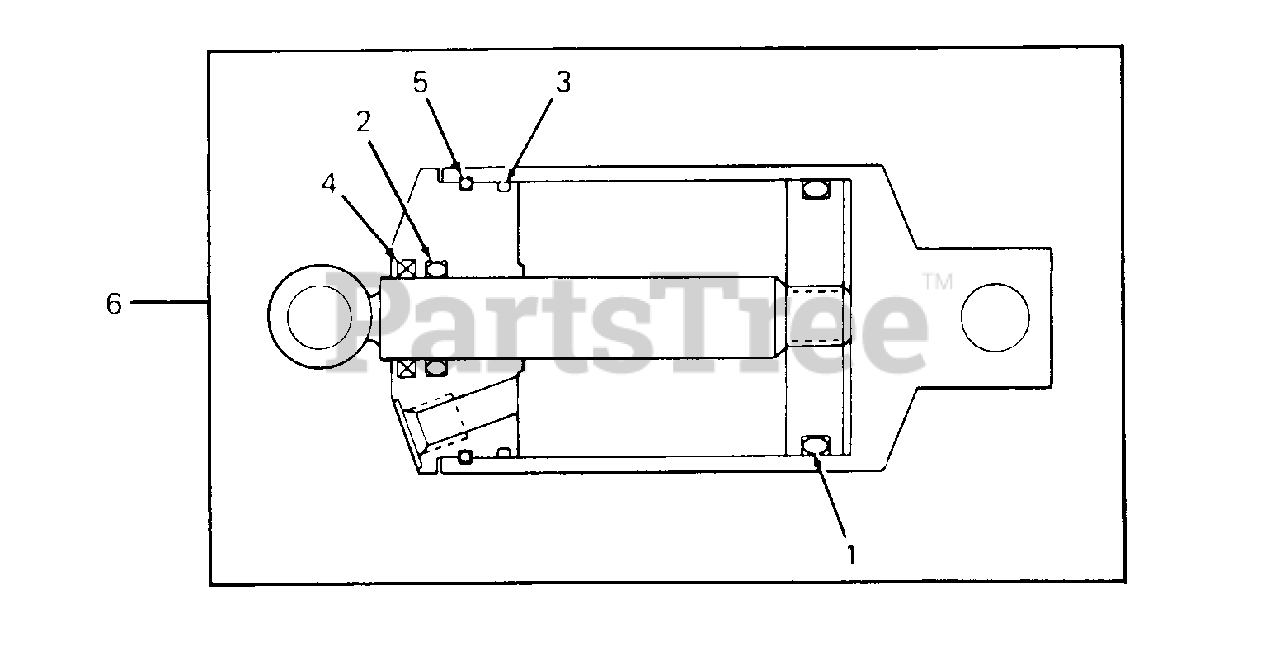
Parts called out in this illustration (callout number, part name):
4	Seal, Hydraulic Cylinder Piston Rod Wiper
5	Retainer, Hydraulic Cylinder Front Head
6	Cylinder, Hydraulic
